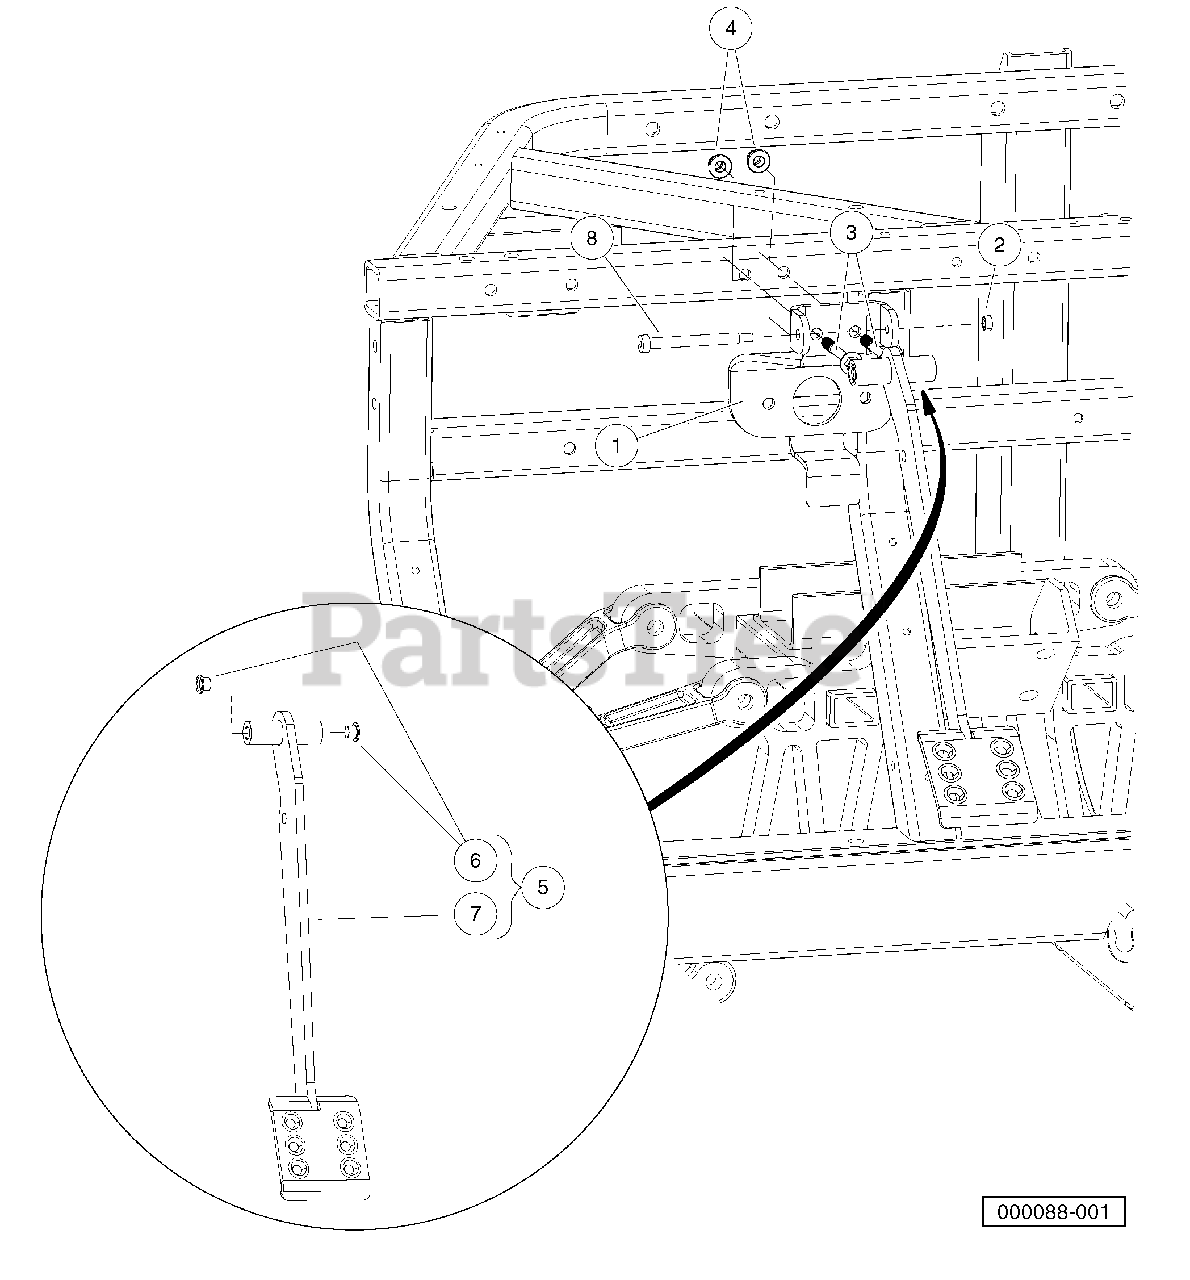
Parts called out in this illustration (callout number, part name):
1	Bracket, Pedal, Brake
2	Nut M6x1 Mech Def Center
3	Bolt Flanged Head, M8 X 1.25 X 65
4	Lock Nut, Flg M8 X 1.25 Nylon
5	Asm, Pedal, Brake, Hung
6	Bushing, Greaseless
7	Weldment, Pedal, Brake, Hung
8	Bolt, Shoulder, M8 X 70, Hc
